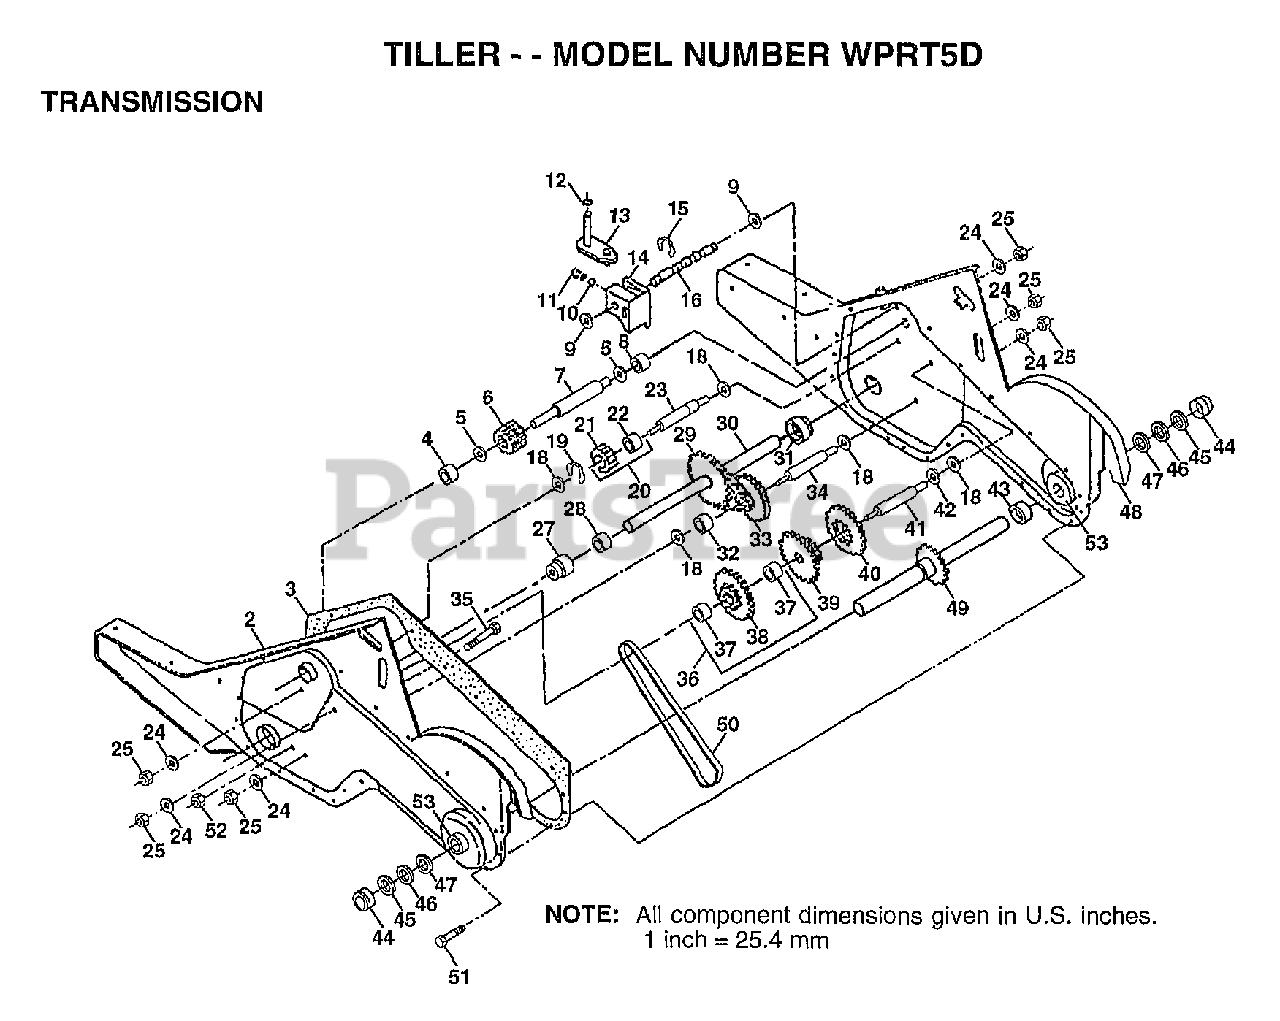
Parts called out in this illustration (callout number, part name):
3	GASKET TI
4	NEEDLE BRNG LT
5	"T, BEARING"
6	GEAR PINION INPUT
7	"SHAFT.INPUT.""D"""
8	"TI, BEARING"
9	WASHER SEAL CRT
11	SPRING-SHIFT CRT
12	O-RING TI
13	BRACKET ASM SHIFT
14	SHIFT FORK TI
15	KLIP RING
16	SHAFT.SHIFT.4.250
18	WASHER
19	KLIP RING
20	GEAR ASSY CRT
21	GEAR-REV IDLR CRT
22	NEEDLE BEARING TI
23	SHAFT CRT
24	LOCKWASHER
25	NUT.ASF.HEX.7/16
27	BEARING.SHAFT.LH.
28	BUSHING TI
29	CHAIN CRT
31	BEARING.SHAFT.RH.
32	SPACER TI
33	SPRCKT 8 GEAR CRT
34	SHFT 2ND RED. CRT
35	SCRW WHIZ LOK CRT
36	SPROCKET ASM.
37	BEARING
39	GEAR TI
40	GEAR TI
41	REDUCTION SHFT TI
42	BRNG RACE
43	SPACER TI
44	CUP.FORMED.
45	RING SPIRAL CRT
46	SEAL RING RUBBER
47	OIL SEAL STD
49	TINE SHAFT
50	CHAIN.50 LINK TI
51	SCREW CRT
52	NUT.HEX.5/16-18
